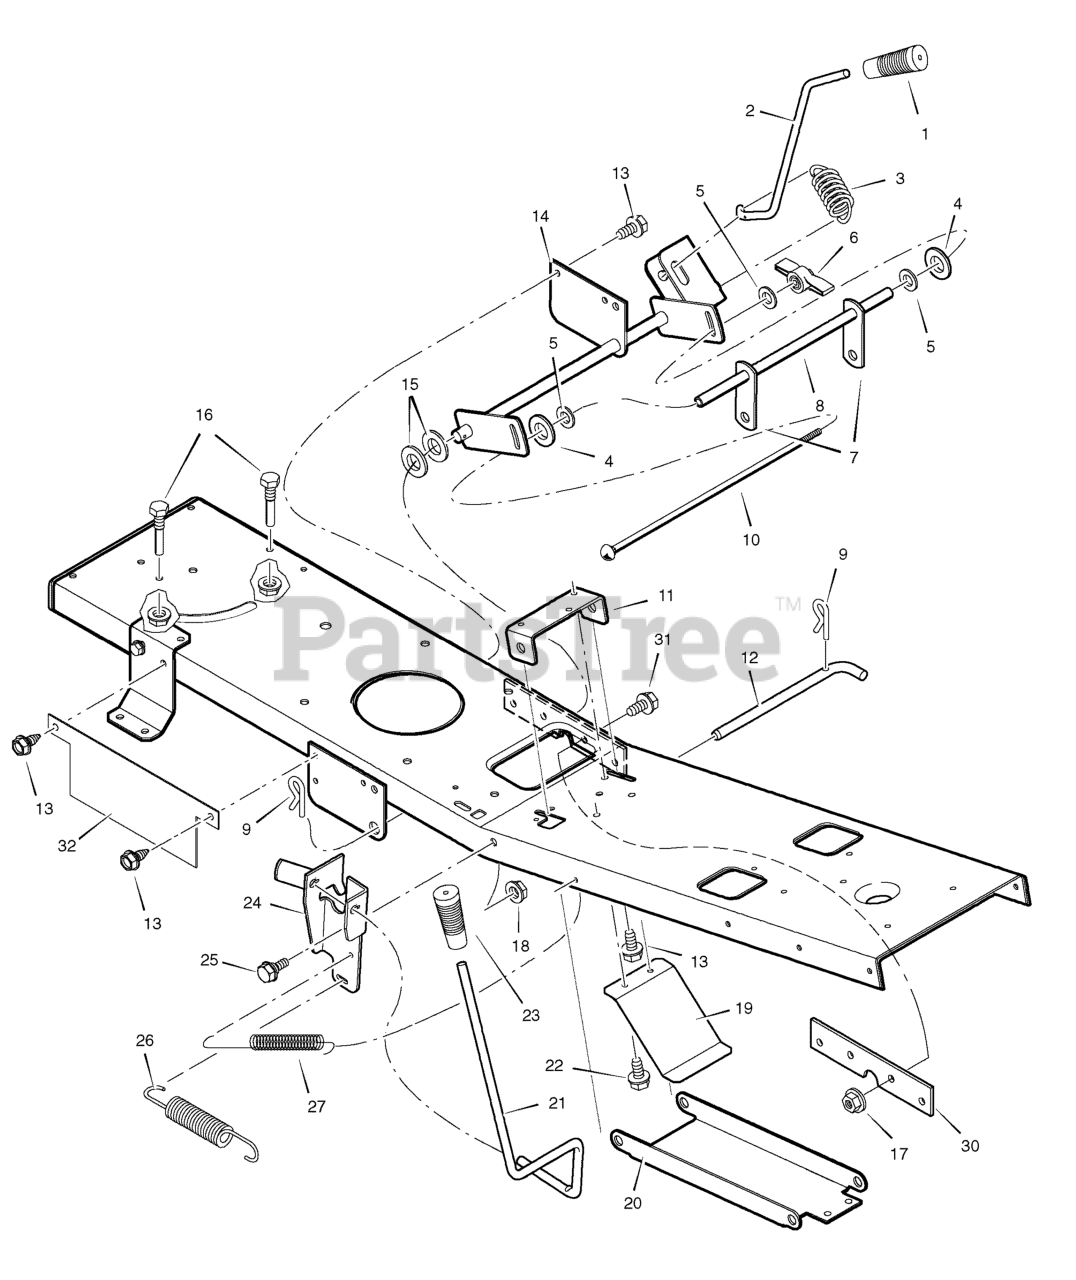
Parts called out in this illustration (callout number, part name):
1	GRIP, Lift Lever
2	LEVER, Lift
3	SPRING, Extension
4	PAD, Friction
6	WINGNUT
8	TUBE, Spacer
9	PIN, Hair
10	BOLT, Carriage
11	BRACKET, Front Hanger Pivot
12	PIN, Front Hanger
14	ARM ASSEMBLY, Lifter
16	SCREW, Guide
17	NUT, Flange
18	NUT, Flange
19	SPRING, Leaf
20	HANGER, Front
21	LEVER, PTO
23	GRIP, PTO
24	BRACKET, PTO
25	BOLT, Shoulder
26	SPRING, Extension
27	SPRING, Extension
30	PLATE, Reinforcement
32	GUARD, Right Rear
